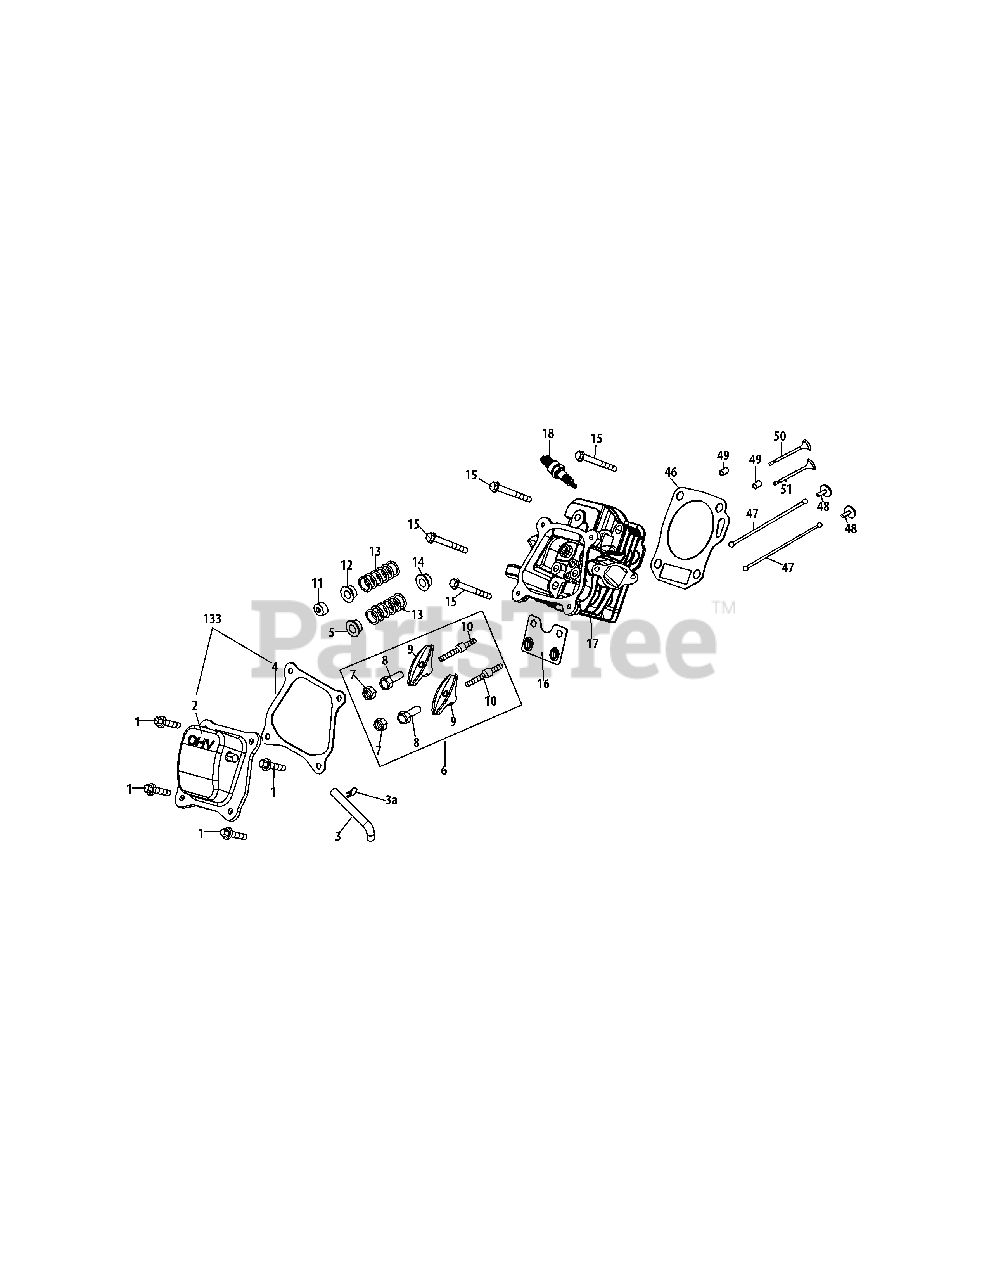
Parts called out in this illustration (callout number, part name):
1	Bolt M6×16
2	Valve Cover
3	Breather Hose
4	Valve Cover Gasket
5	Retainer, In.Valve Spring
6	Rocker Arm Assembly
7	Nut,Pivot Locking
8	Adjusting Nut, Valve
9	Rocker Arm
10	Bolt,Pivot
11	Adjuster,Exh Valve
12	Retainer,Ex.Valve Spring
13	Valve Spring
14	Intake Valve Seal
15	Bolt M8×55
16	Push Rod Guide
17	Cylinder Head Assembly
18	Spark Plug
46	Gasket, Cylinder Head
49	Dowel Pin 10×16
50	Exhaust Valve
51	Intake Valve
133	Valve Cover Kit
